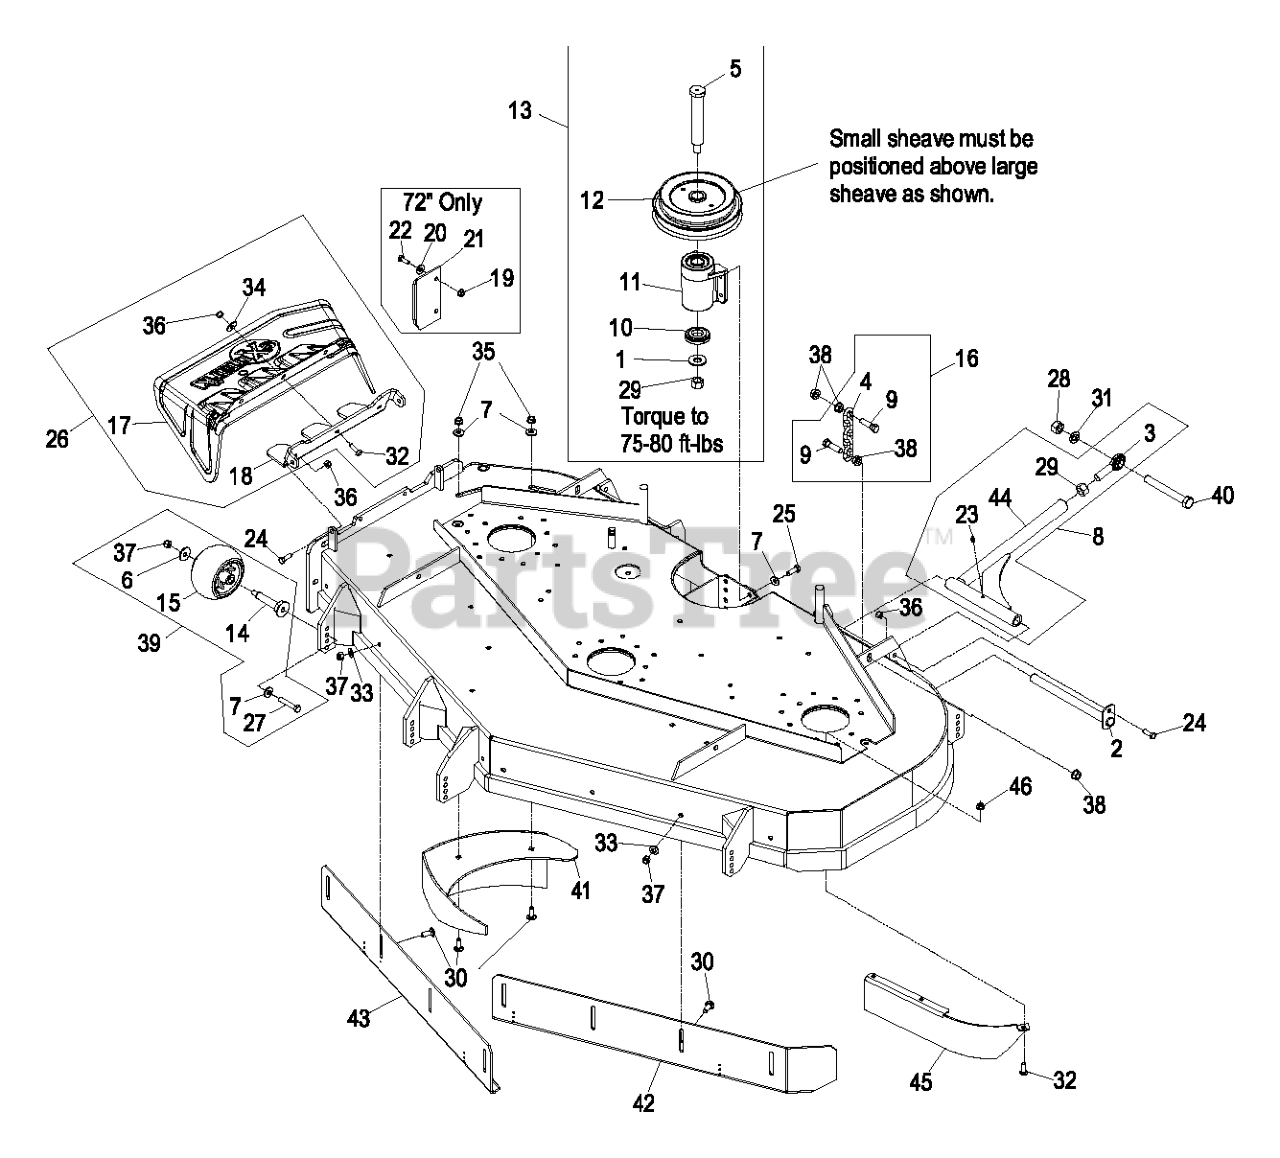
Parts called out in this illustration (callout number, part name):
1	WASHER-SPRING
2	PIN-STRUT
3	BALLJOINT-SPHERICAL
4	CHAIN-LIFT, DECK
5	JACKSHAFT
7	WASHER-BELLEVILLE
8	ASM,DECK STRUT XS 60
9	SCREW-HH
10	SPACER-GUARD, BOTTOM
11	KIT, JACKSHAFT ASSY
12	SHEAVE, JACKSHAFT DOUBLE
13	KIT,JACKSHAFT 60/72-3750
15	ROLLER-SCALP, ANTI
16	DECK CHAIN ASM
17	CHUTE,DISCHARGE LZ
18	HINGE,DISCHARGE CHUTE
20	WASHER-FLAT
21	DEFLECTOR,DISCHARGE
22	SCREW-HH
23	FITTING-GREASE
24	SCREW-HH
25	SCREW-HH
26	ASM, DISCHARGE CHUTE
27	SCREW-HH
28	NUT-HEX
29	NUT-HEX
30	SCREW-CARR
31	WASHER-LOCK
32	SCREW-CARR
33	WASHER-FLAT
34	WASHER-FLAT
35	NUT-HHF, WHIZ
36	NUT-LOCK, NI
37	NUT-LOCK, NI
40	SCREW-HH
41	WLD,DOGLEG 605
42	WLD,BAFFLE FRT ADJ LH 605
43	WLD,BAFFLE FRT ADJ RH 605
45	BAFFLE,SCROLL 605
46	NUT-HF, NI
